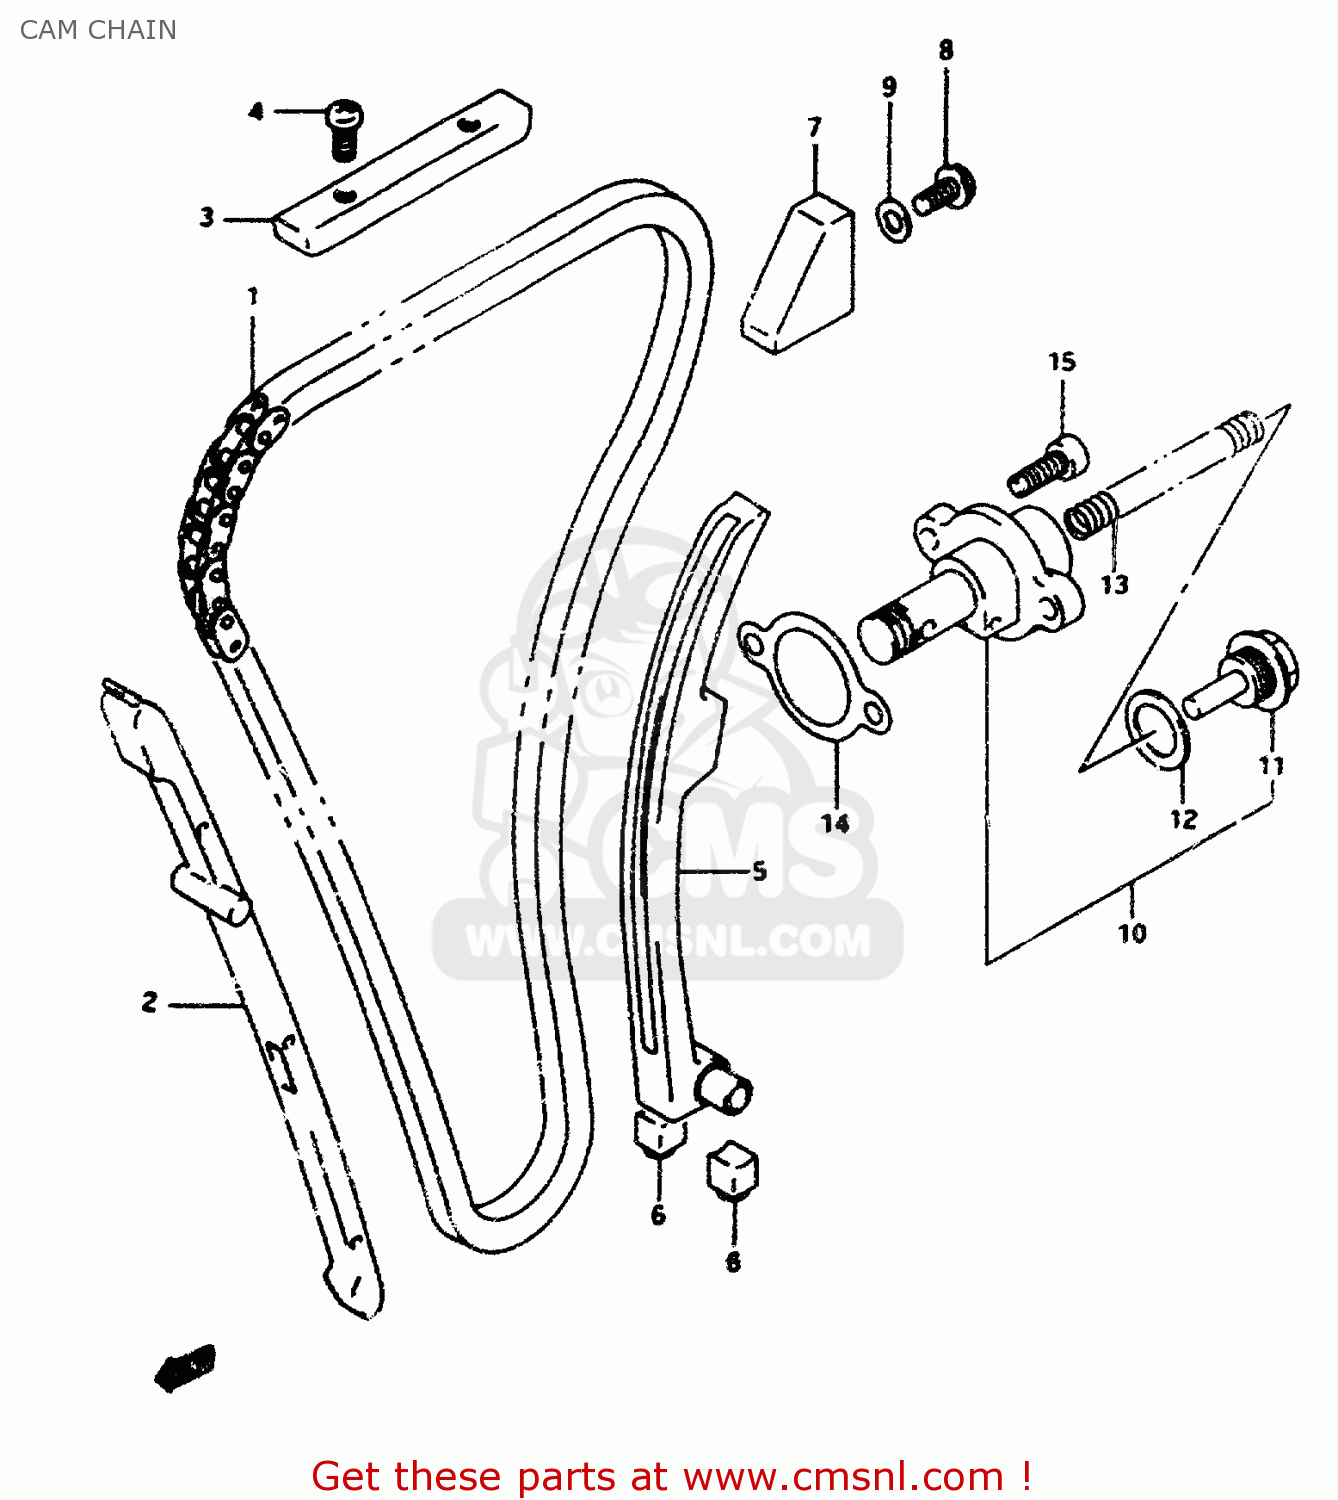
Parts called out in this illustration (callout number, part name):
1	CHAIN,CAMSHAFT DRIVE
2	GUIDE,CAM CHAIN NO.1
3	GUIDE,CAM CHAIN NO.2
4	SCREW
5	TENSIONER,CAM CHAIN
6	CUSHION,CAM CHAIN TENSIONER
7	GUIDE,CAM CHAIN NO.3
8	BOLT
9	GASKET(5.8X13X1.2) (NAS)
10	ADJUSTER ASSY,TENSIONER
11	PLUG
12	GASKET (NAS)
13	SPRING
14	GASKET,TENSIONER ADJUSTER (NAS)
15	BOLT
